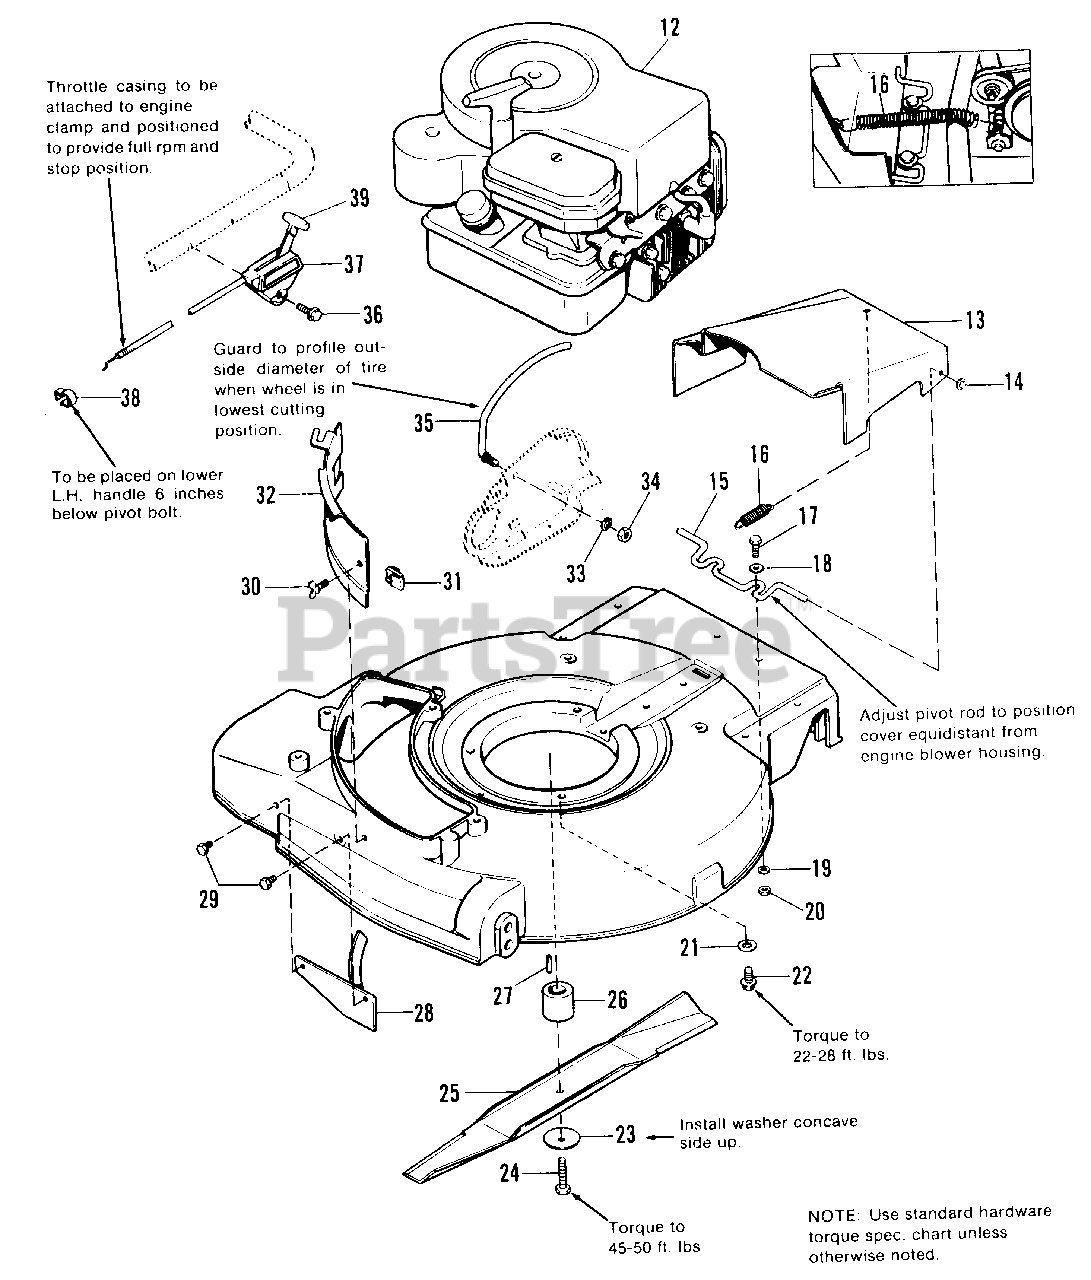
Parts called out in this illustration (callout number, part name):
13	COVER, Belt
17	CAPSCREW, Hex Hd., 1/4-20 x 3/4
18	WASHER, Plain, 3/16
19	LOCKWASHER, 1/4
20	NUT, Hex, Full, 1/4-20
21	LOCKWASHER, Int. Tooth, 3/8
22	SCREW, Taptite, 3/8-16 x 1
23	WASHER, Spring
24	CAPSCREW, Hex Hd., 3/8-24 x 1-1/2
25	BLADE, 21"
26	ADAPTOR, Blade
27	KEY, Woodruff, #6
28	STONE GUARD ASSY.
29	SCREW, Taptite, 1/4-20 x 1/2 (Mfg. No. 1690512)
30	SCREW, Thumb, 1/4-20 x 5/8
31	NUT, Speed
32	BAFFLE (Mfg. No. 1690511 & 512)
33	LOCKWASHER, 5/16 (Mfg. No. 1690511 & 512)
34	NUT, Hex, Full, 5/16-18
35	GUARD, Bag (Mfg. No. 1690511 & 512)
36	SCREW, Taptite, 1/4-20 x 1
37	CONTROL, Throttle
38	CLAMP, Spring
39	KNOB
